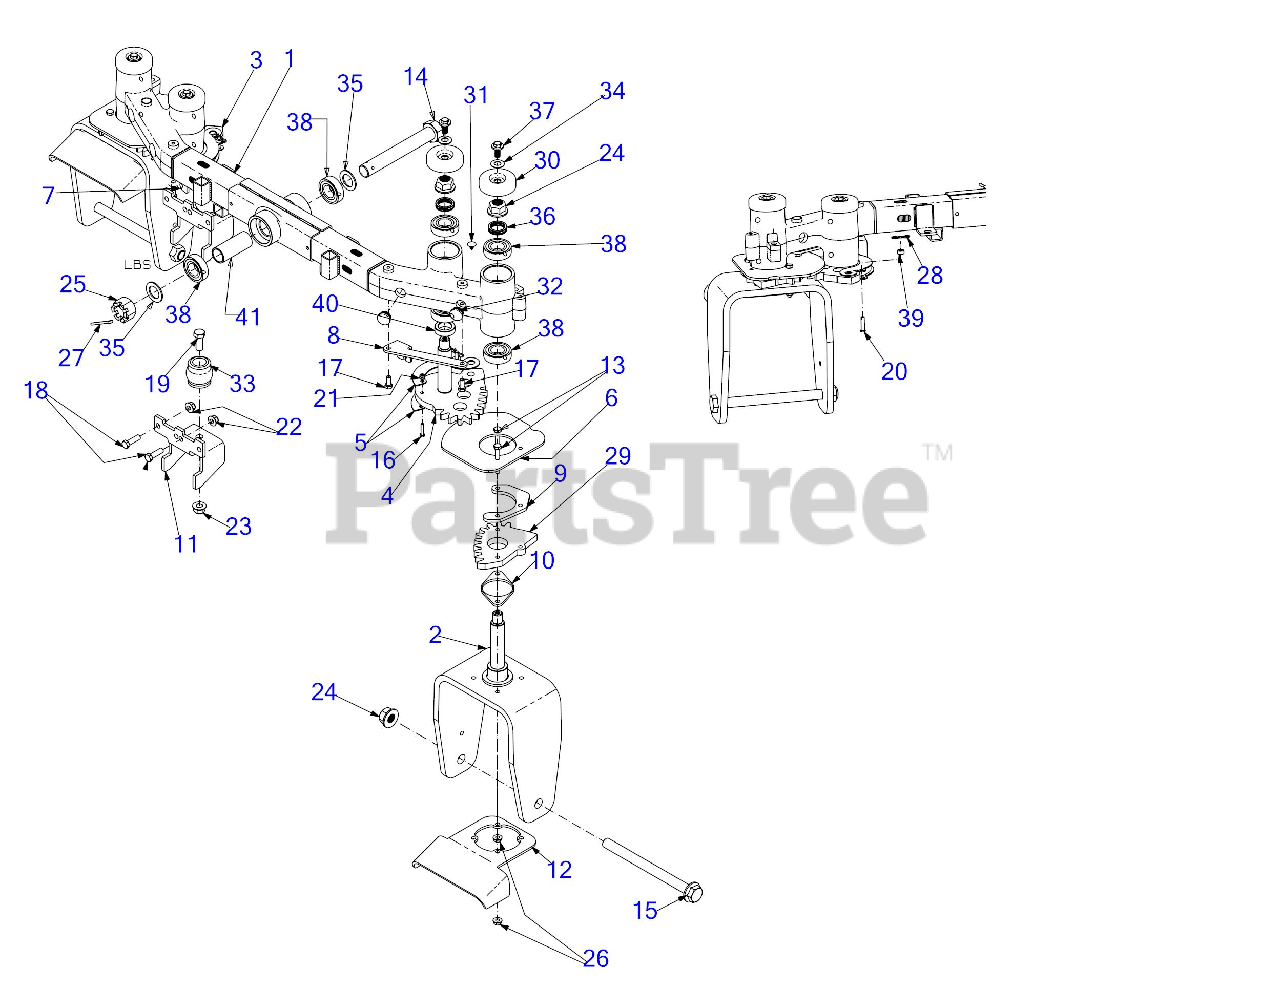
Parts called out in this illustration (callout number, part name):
4	RIGHT HAND STEERING GEAR ASSEMBLY
10	LOWER GEAR SPACER PLATE
13	HEX SCREW 5/16-18 x 2.25 GR5
14	HEX HEAD SCREW 1-14 X 7 GR5
15	SCREW 3/4-16 x 9.00 GR5
16	SCREW #10-24 x 1.00 GR5.1
17	SCREW 5/16-18 x .750
18	SCREW 3/8-16 x 1.25 GR5
19	SCREW 1/2-13 x 1.25 GR5
20	CLEVIS PIN .25 x 1.00
24	FLANGE LOCK NUT 3/4-16 TOP LOCK
25	CASTLE NUT 1.0-14 GR5
26	HEX FLANGE NUT
27	COTTER PIN
28	BOW TIE COTTER PIN 1/4-5/16
29	STEERING GEAR YOKE
30	AXLE CAP 2.5"
31	RATCHET CLIP
33	AXIAL BUMPER
34	BELL WASHER
35	FLAT WASHER 1.031 X1.62 X.095
36	WAVE WASHER
38	BALL BEARING 1.0 X 52 X 15
41	SPACER 1.00 X 1.25 X 2.99
